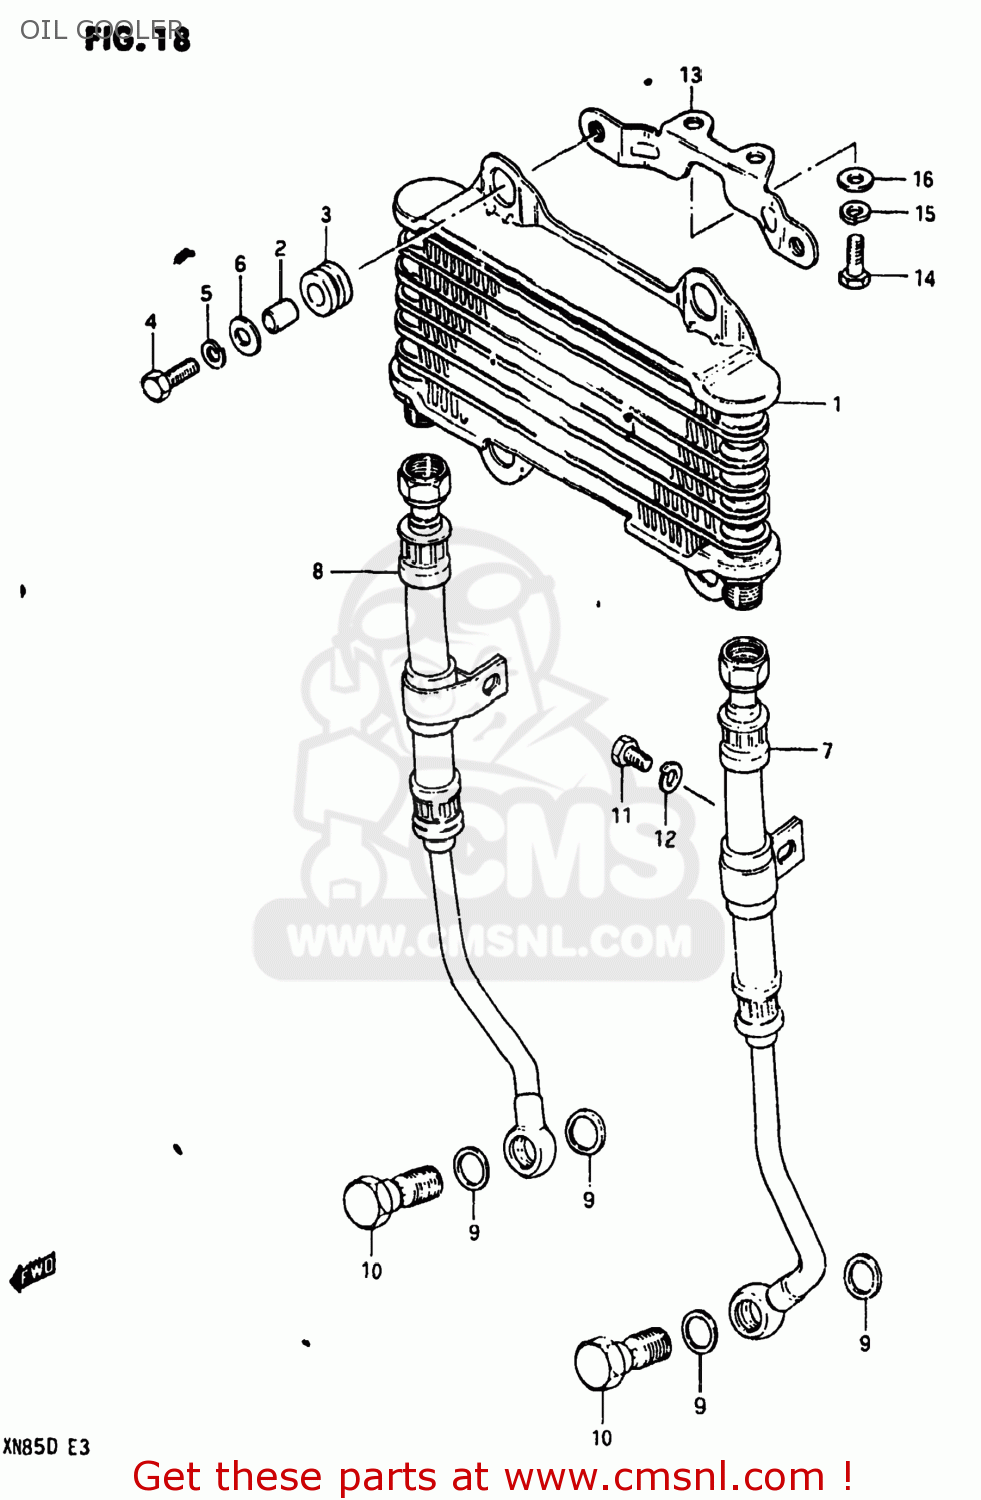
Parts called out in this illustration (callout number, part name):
1	COOLER ASSEMBLY,ENGINE OIL
2	SPACER (6.8X10X10)
3	CUSHION
4	BOLT
5	LOCK WASHER
6	WASHER
7	HOSE,ENGINE,LEFT
8	HOSE,ENGINE,RIGHT
9	GASKET(14X20X1.5) (NAS)
10	BOLT UNION
11	BOLT
12	LOCK WASHER
13	BRACKET,OIL COOLER
14	BOLT, UPPER
15	LOCK WASHER
16	WASHER
